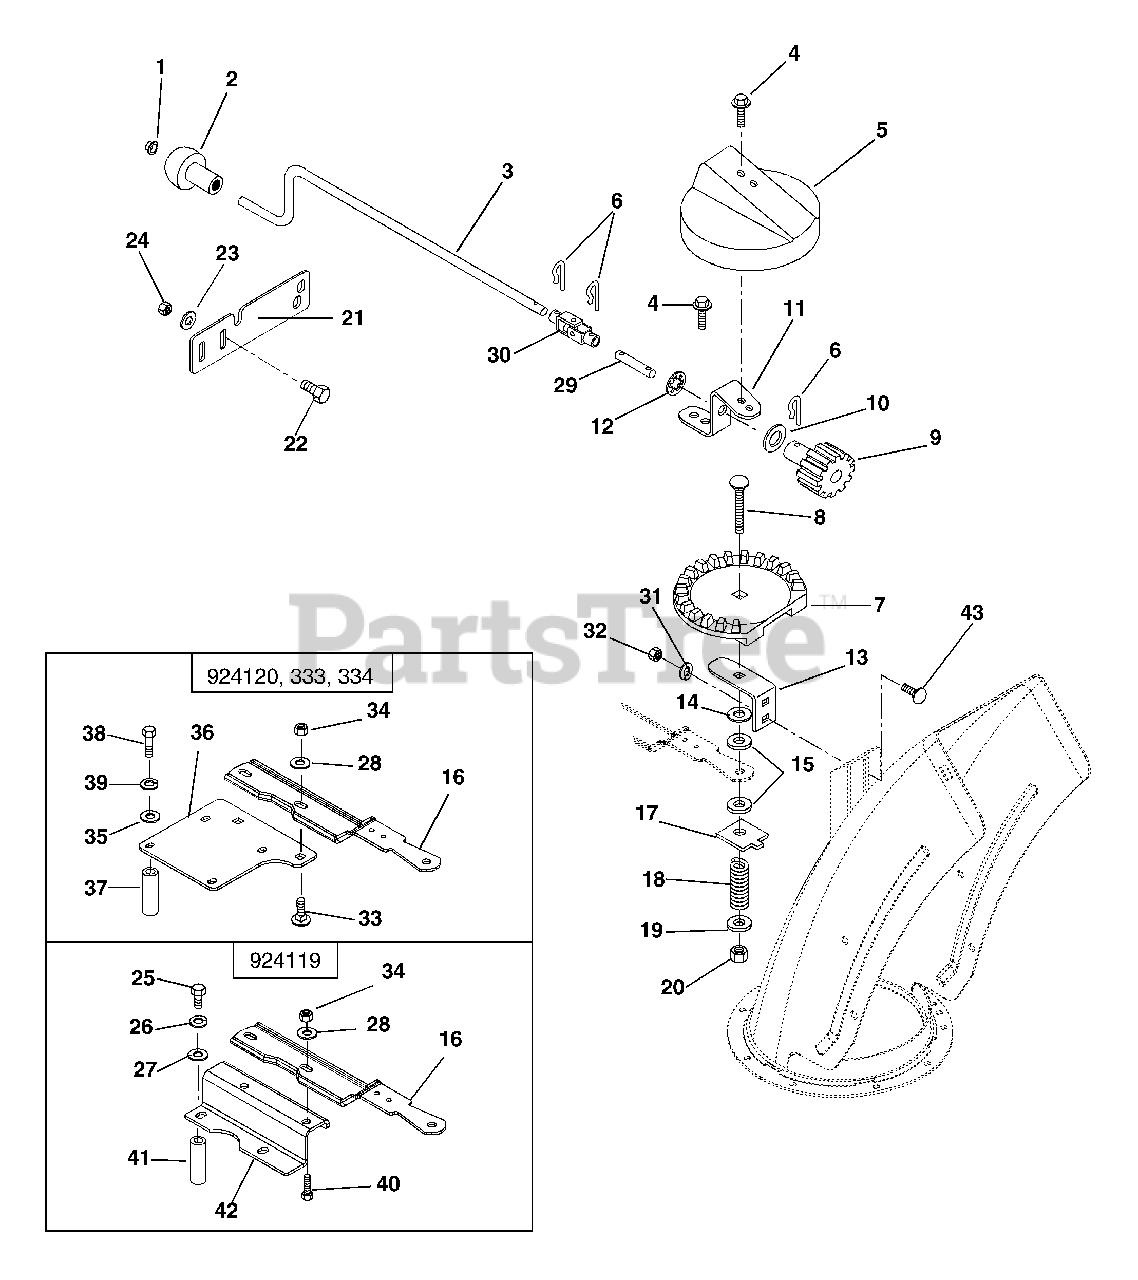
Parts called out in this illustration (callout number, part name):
1	CAP, 3/8 ROD YWZC
3	CRANK, CHUTE
4	@SCR-TAP .25-20X.50 HWH TR YWZ
5	GEAR COVER
6	PIN, SPRING CLIP
7	CHUTE GEAR
8	@BLT-RDHDSQNK .38-16X2.50 G5YZ
9	PINION GEAR W/BRACKET
10	WSHR-FL-STL .630X1.005X.062 YZ
11	BRACKET-GEAR
12	PUSHNUT .625
13	GEAR STRAP
14	WSHR-FL-STL .380X1.50X.062 YWZ
15	FRICTION WASHER
16	BRACKET, CHUTE SUPPORT
17	FRICTION PLATE
18	SG-COMP .187X.56X1.62
19	@WSHR-FL-STL.406X.812X.065 YWZ
20	@NUT-LK-CTR .38-16 YWZC
21	BRACKET, CHUTE CRANK SUPPORT
22	@BLT-HEX .25-20X.50 GR5 YWZC
23	@WSHR-FL-STL.312X.734X.065 YWZ
24	@NUT-LK-CTR .25-20 YWZC
25	@BLT-HEX .31-18X1.25 GR5 YWZC
26	@WSHR-LK .31X.078 REG YWZC
27	@WSHR-FL-STL.344X.688X.065YWZC
28	@WSHR-FL-STL.312X.734X.065 YWZ
29	PIN, CONNECTOR
30	UNIVERSAL JOINT ASS'Y
31	@WSHR-LK .25X.062 REG YWZC
32	@NUT-HEX .25-20 YWZC
33	@BLT-RDHDSQNK .31-18X.75 G5YZ
34	@NUT-LK-CTR .31-18 YWZC
35	@WSHR-FL-STL.281X.62X.065 YWZC
36	BRACKET, ENGINE
37	SPACER, TUBE
38	@BLT-HEX .25-20X.75 GR5 YWZC
39	@WSHR-LK .25X.062 REG YWZC
40	@BLT-HEX .31-18X.75 GR5 YWZC
41	SPACER .322X.626X.50
42	BRACKET, ENGINE-8&10
43	@BLT-RDHDSQNK .25-20X.75 G5YZ
